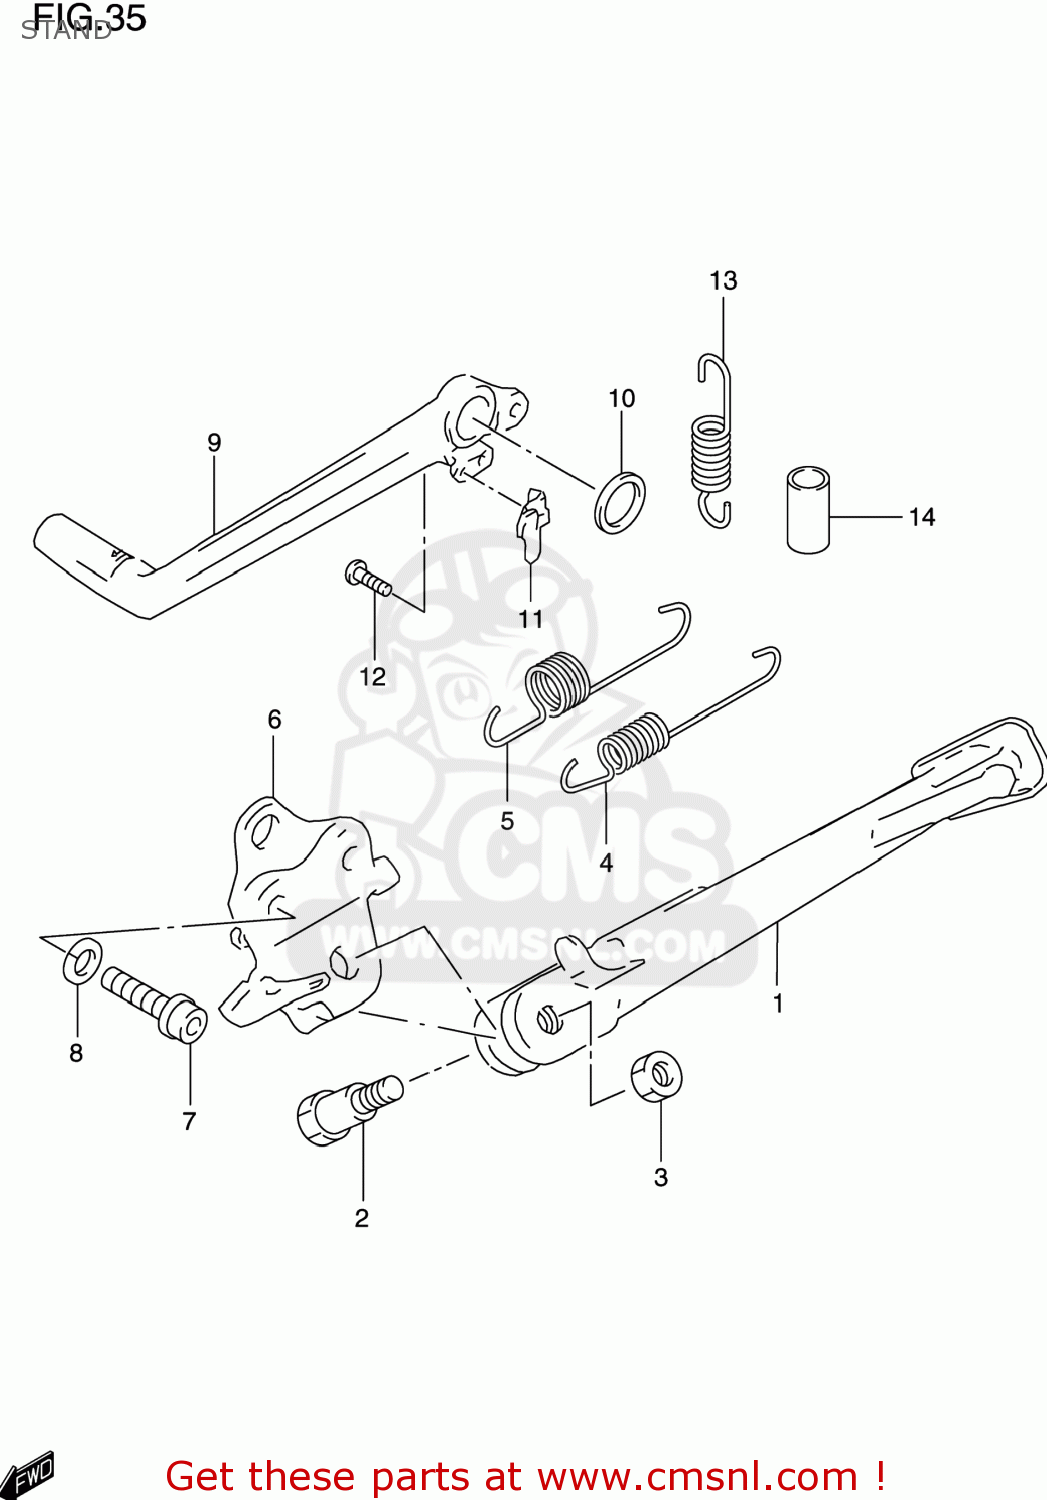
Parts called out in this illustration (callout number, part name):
1	STAND,PROP
2	BOLT(10X34)
3	NUT
4	SPRING
5	SPRING
6	BRACKET,PROP STAND
7	BOLT
8	LOCK WASHER
9	PEDAL,BRAKE
10	WASHER(18X24X1)
11	HOOK,RETURN SPRING
12	SCREW
13	SPRING
14	TUBE,BRAKE SPRING GUIDE
